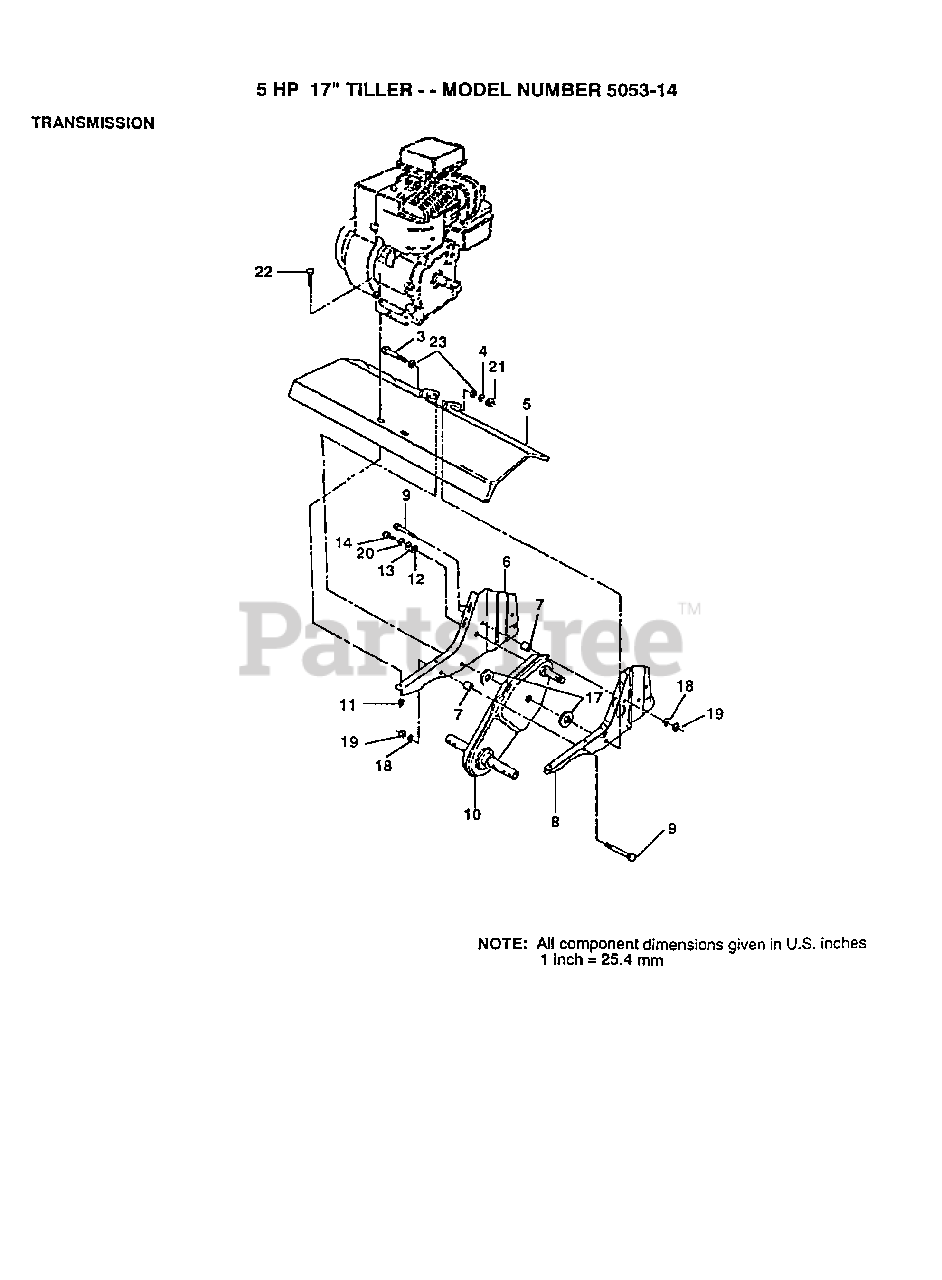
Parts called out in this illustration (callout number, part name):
3	BOLT.3/8-24X3.75
4	LOCKWASHER
5	"SHIELD,TINE TI"
7	SPLIT SPACER RT
8	BRACKET.ENG.LH.
12	WASHER
13	WASHER
14	BOLT
18	LOCKWASHER
19	NUT.HEX.5/16-18
20	LOCKWASHER
21	GRIPCO NUT
22	BOLT.HEX.5/16-1.5
23	WASHER
